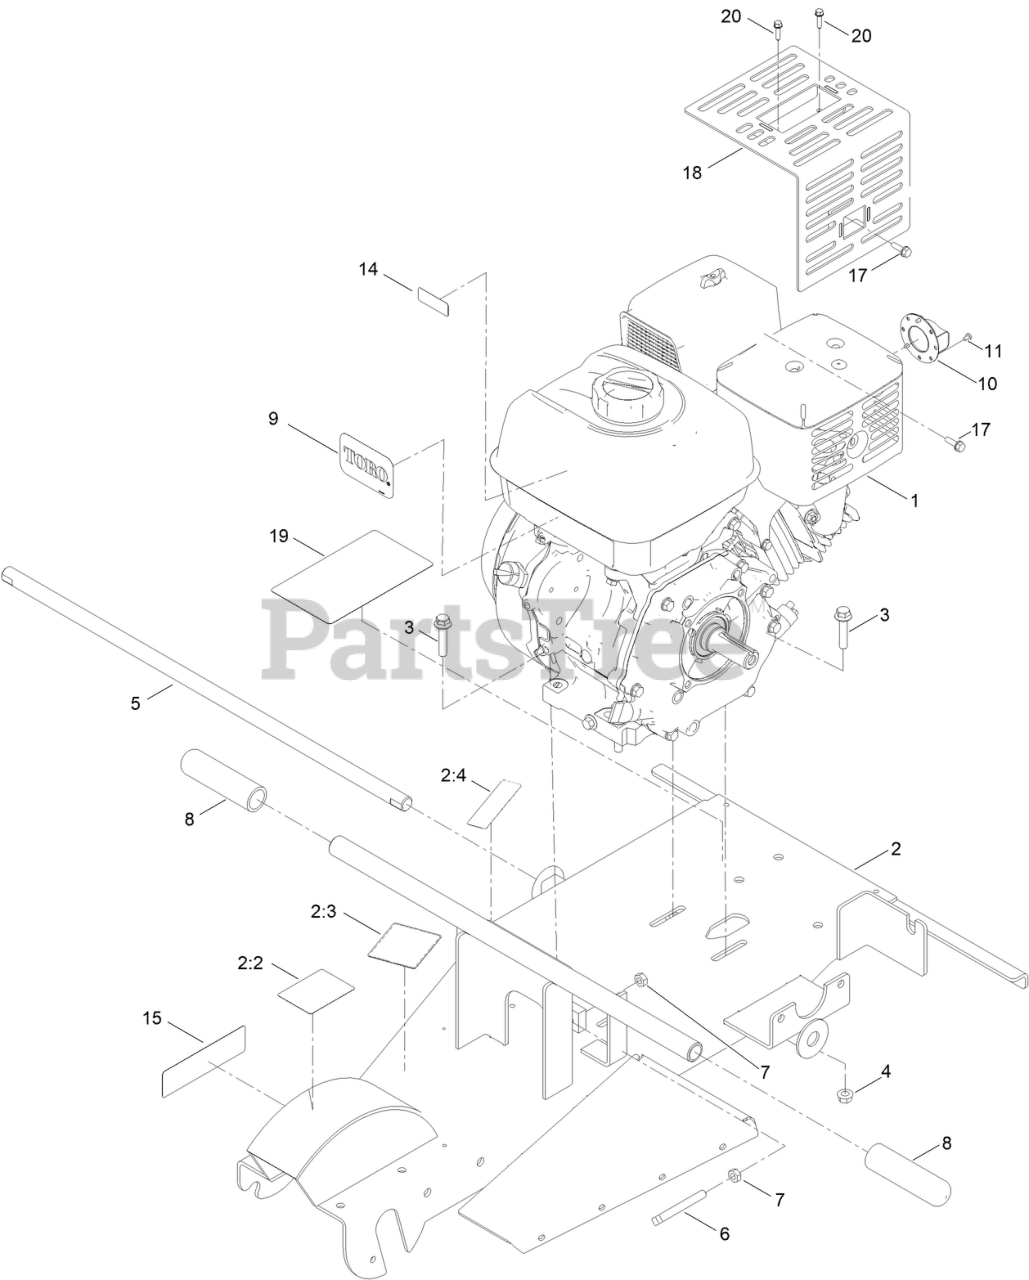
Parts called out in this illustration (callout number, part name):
2	FRAME ASM, SUNBELT
2:2	DECAL-DANGER
2:3	DECAL-CAUTION
2:4	DECAL-ARRESTOR, SPARK
3	SCREW-HHF
4	NUT-HF
5	BAR-AXLE
6	SCREW-SET, SQH
7	NUT-HEX
8	GRIP-HANDLE
9	DECAL
10	DEFLECTOR-EXHAUST, HONDA
11	SCREW-SELF TAPPING
14	DECAL-WARNING, ETHANOL
15	DECAL-ROTATE TOOTH
18	GUARD-MUFFLER
19	DECAL-SERVICE
20	SCREW-HWH THD ROLL
